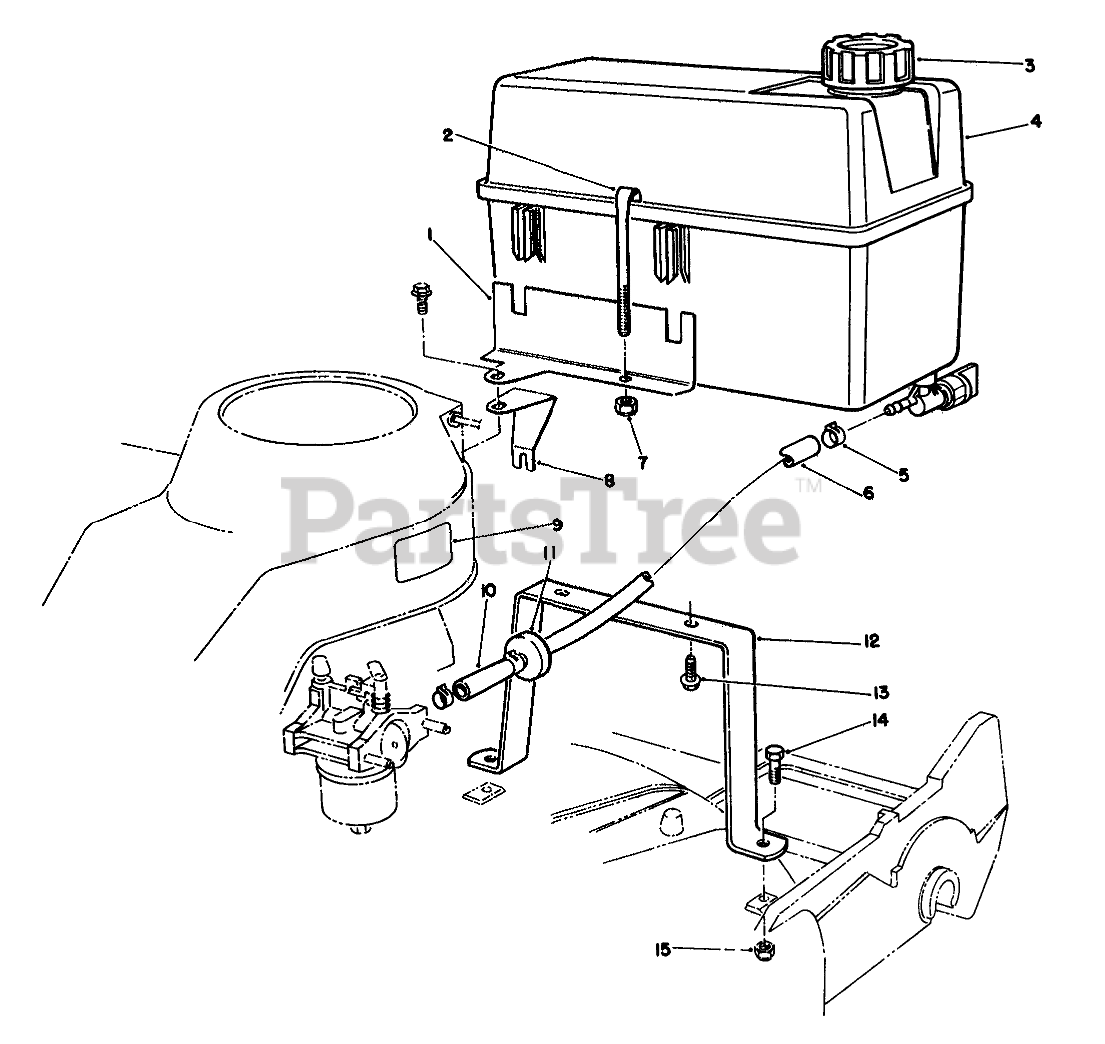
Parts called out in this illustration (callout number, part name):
1	Bracket Tank
2	RETAINER - FUEL TANK
3	GAS CAP ASM
4	Tank-Gas
5	CLAMP-FUEL LINE
6	HOSE-FUEL
7	NUT-LOCK, NI
8	Support-Bracket
9	DECAL - FUEL
10	LINE-GAS
11	FILTER-FUEL
12	TANK BASE
13	SCREW-HWH
14	SCREW-HH
15	NUT-LOCK, NI
